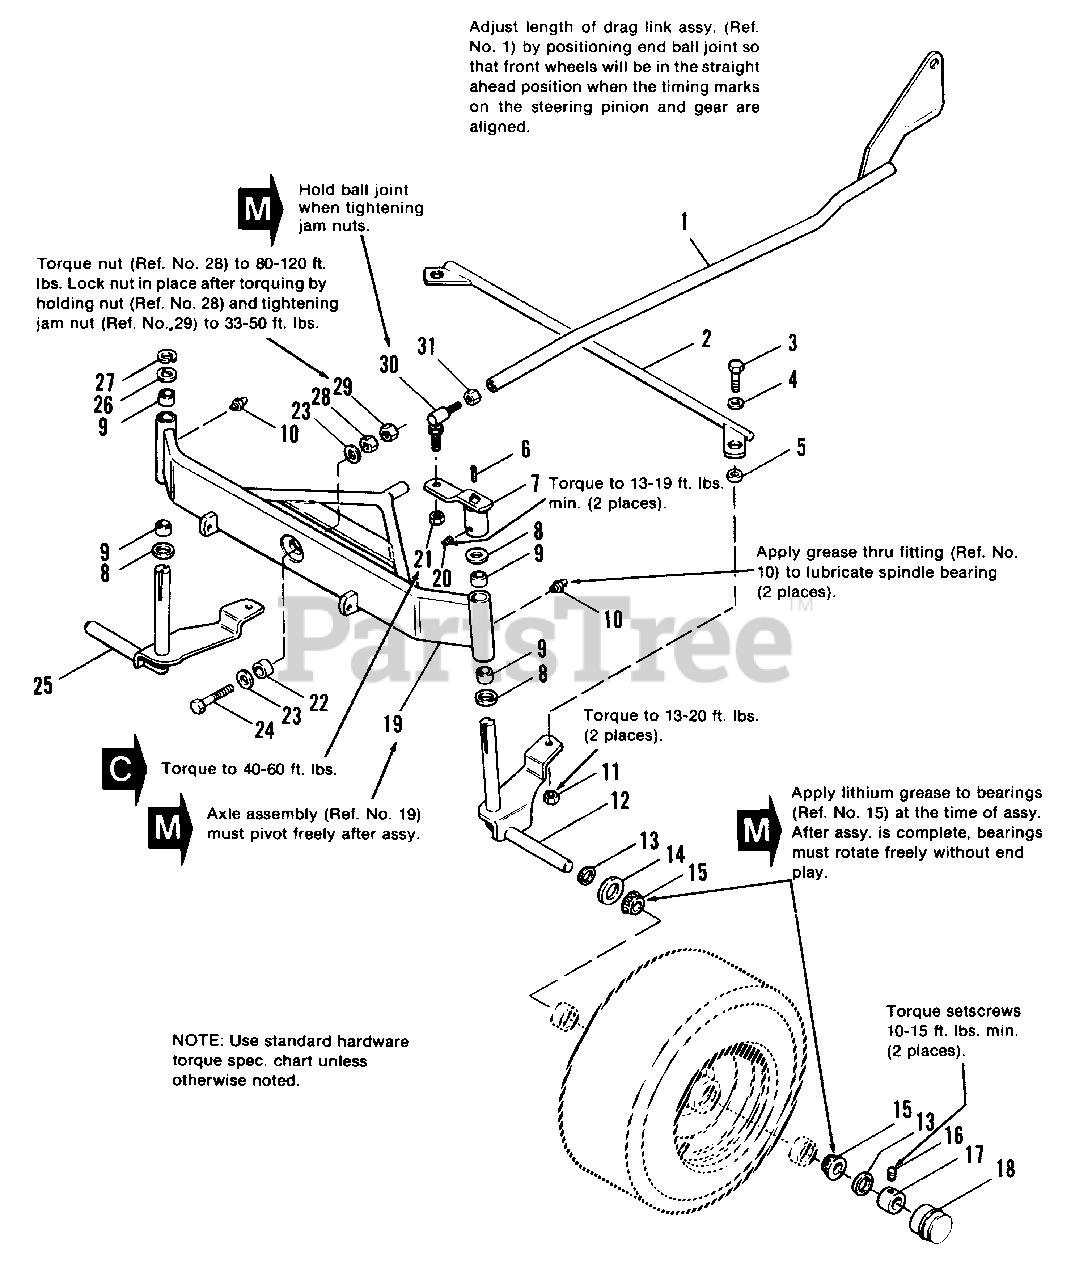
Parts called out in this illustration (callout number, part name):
1	LINK ASSY., Drag
2	ROD ASSY., Tie
3	CAPSCREW, Hex Hd., 3/8-16 x 1
4	WASHER, Plain, 3/8
6	KEY, Square
7	ARM ASSY., Steering
10	FITTING, Grease
11	LOCKNUT, Hex, 3/8-16
12	SPINDLE ASSY., LH
15	CONE, Bearing
16	SETSCREW, 5/16-18 x 5/16
17	COLLAR, Set
18	CAP, Hub
19	AXLE ASSY., Front
20	SETSCREW, 5/16-18 x 1/2
21	LOCKNUT, Hex, 1/2-20
23	WASHER, Plain, 1/2
24	CAPSCREW, Hex Hd., 1/2-13 x 2-1/4
25	SPINDLE ASSY., RH
27	RING, Retaining
28	LOCKNUT, Hex, 1/2-13
29	LOCKNUT, Hex, Jam, 1/2-13
30	BALL, Joint
31	LOCKNUT, Hex, Jam, 1/2-20
